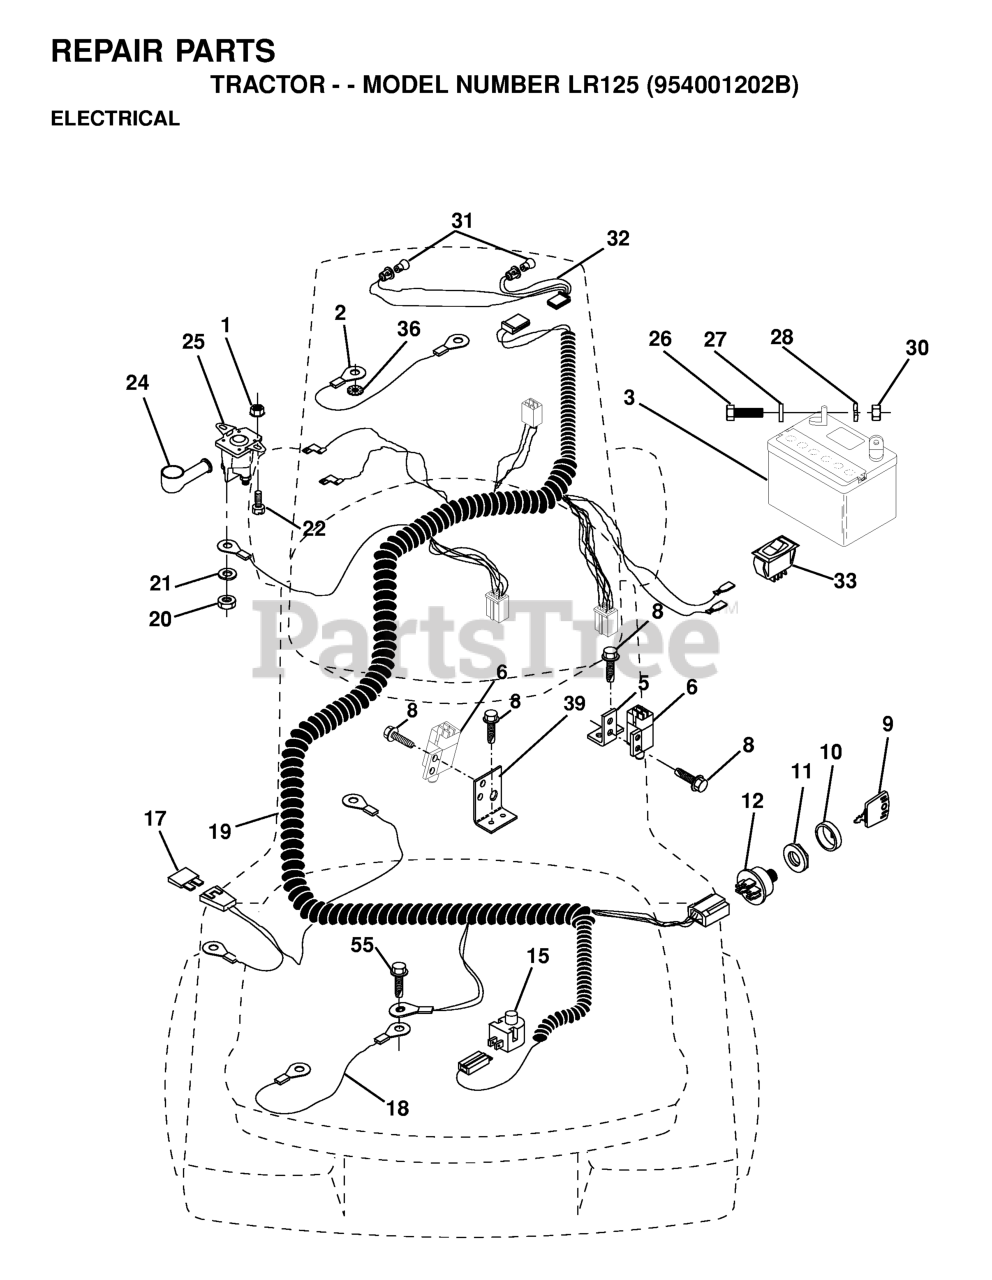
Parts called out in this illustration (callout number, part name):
1	Nut, Keps Blk Hex 1/4-20 UNC
2	CABLE.BATTERY.6GA.16"RED
3	REPL BY 532 12 38-99
5	BRACKET LT
6	SWITCH INTERLOCKT
9	KEY MLD GEN DELTA
10	COVER SWITCH KEY
11	NUT, IGNITION
12	IGNITION SWITCH
15	RP.SWITCH.PLUNGER.NC.GRAY
18	CABLE ASSY
19	HARNESS IGN LR NLA
20	NUT
21	LOCKWASHER
22	BOLT
24	TERMINAL COVER
25	SOLINOID
26	BOLT.HEX.1/4.X.3/4.DICHROMATE
28	LOCKWASHER
30	NUT
32	HARNESS HEADLIGHT
36	Washer, Lock, Internal Tooth 1/4
55	Screw 5/16-18 x 1/2 Hex, Self Tapping 5/16-18 x 1/2
